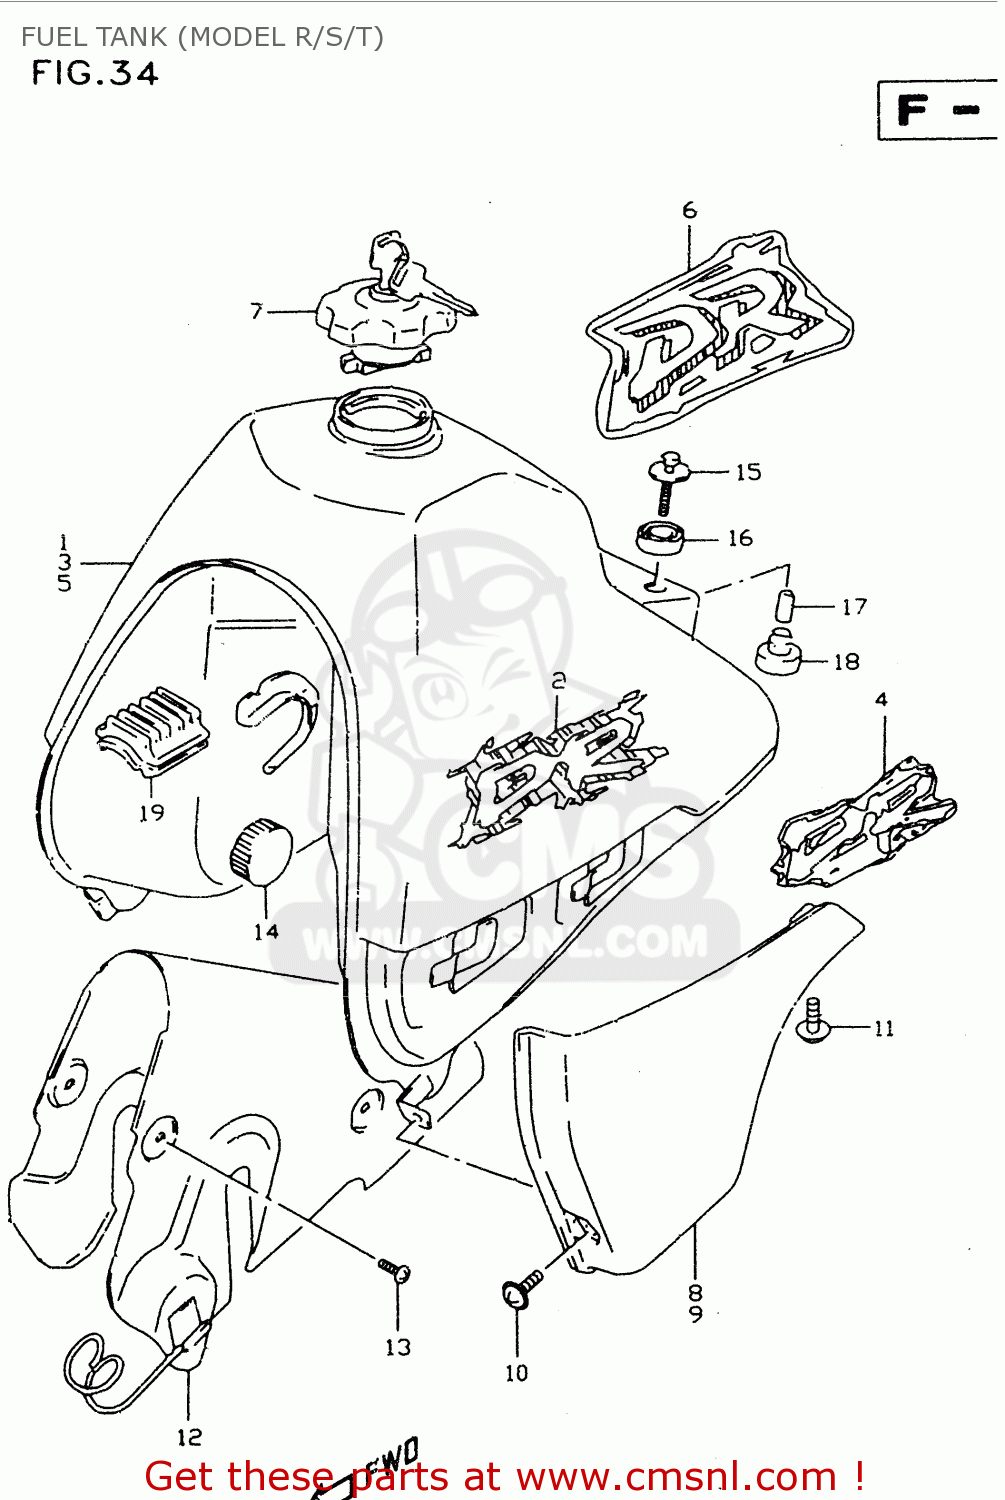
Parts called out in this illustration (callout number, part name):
1	TANK ASSY, FUEL (WHITE)
2	TAPE SET, FUEL TANK
3	TANK ASSY, FUEL (WHITE)
4	EMBLEM SET,FUEL TANK
5	TANK ASSY, FUEL (WHITE)
6	TAPE SET,FUEL TANK
7	CAP SET,FUEL TANK
8	COVER,FUEL TANK,R
9	COVER,FUEL TANK,L
10	SCREW(6X12)
11	SCREW
12	SHIELD,FUEL TANK
13	BOLT
14	CUSHION
15	BOLT(6X30)
16	CUSHION
17	SPACER
18	CUSHION
19	CUSHION,FUEL TANK FR UPR
